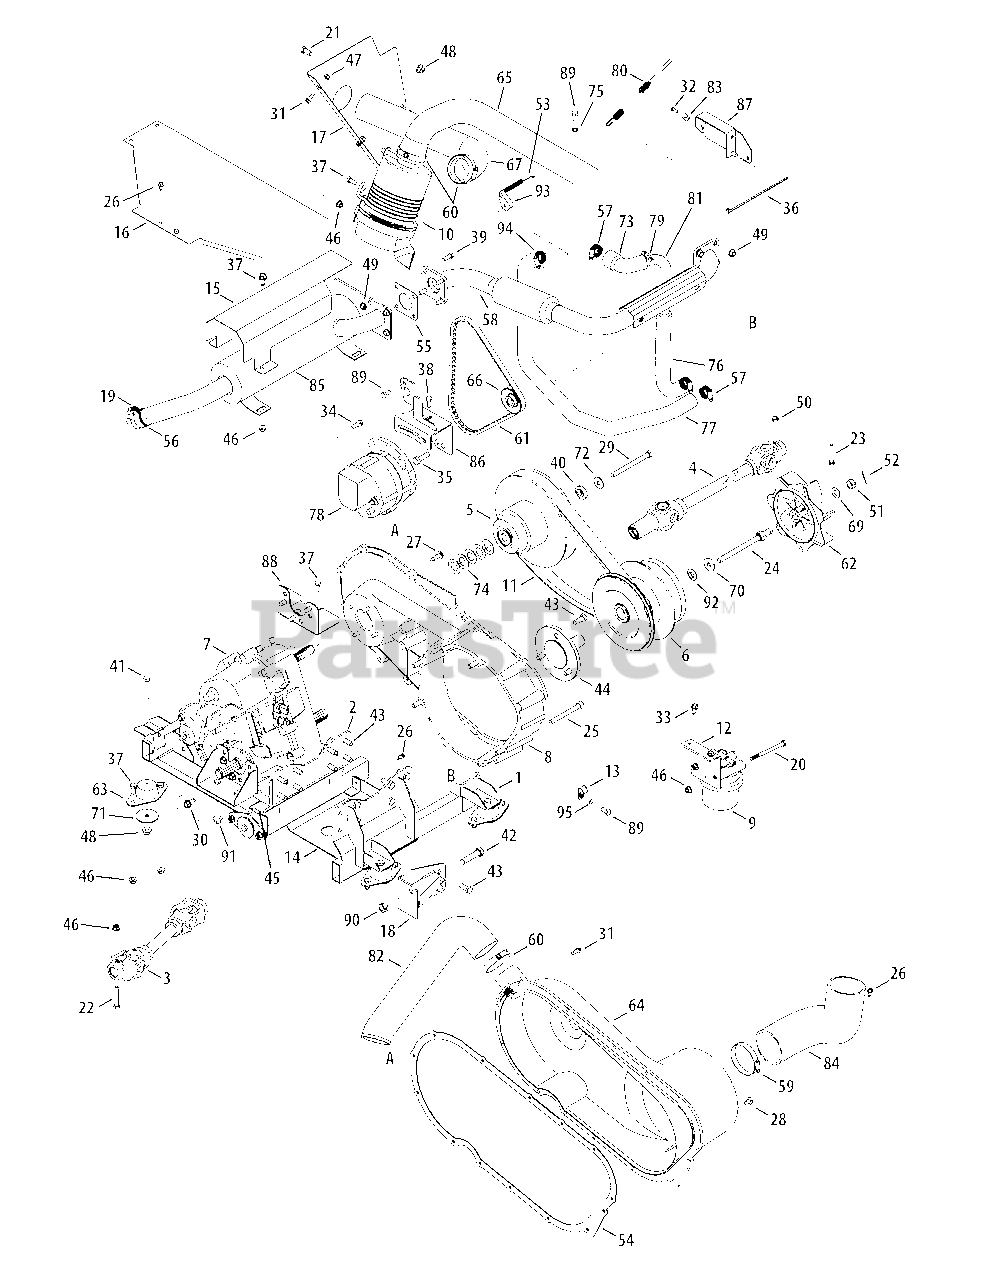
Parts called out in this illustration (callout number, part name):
1	Tray Assembly, Engine, Yanmar
2	Tray Assembly, Engine, Trans
3	Shaft Assembly, Rr/prop
4	Shaft Assembly, Frt/prop, Hilliard
5	Clutch Assembly, Cvt, Driven
6	Clutch Assembly, Driver, Yanmar
7	Case Assembly, Transfer
8	Housing Assembly, Cvt, Machine
9	Filter Assembly, Diesel
10	Filter Assembly, Air Cleaner
11	Belt, Cvt, 4x4
12	Bracket, Fuel Filter, Yanmar
14	Shield, Oil, Engine
15	Exhaust, Shield, Heat
16	Plate, Heat, Shield, Yanmar
18	Bracket Mount, Lower, Alternator
20	Hex Head Screw, 5/16-18, 4.00
21	Hex Head Screw, 3/8-16, .75
22	Hex Head Screw, 5/16-18, 2.00
23	Hex Head Screw, 5/16-18, 1.875
24	Hex Head Screw, 7/16-20, 5.00
25	Screw, M10-1.50
26	Screw, Tt, 1/4-20, 0.500, Hxindwsh
27	Screw, Tt, 5/16-18, 1.000, Hxind.
28	Screw, B, 5/16-12, 0.500, Hxindwsh
29	Hex Head Screw, 3/8-24, 2.50
30	Screw, Tt, 3/8-16, 0.750, Hxindwsh
31	Screw, Tt, 1/4-20, 0.750, Hxindwsh
32	Screw, #10-16, 0.625, Hxindwsh
33	Screw, 5/16-18, 0.750, Hxindwsh
34	Hex Head Screw, 5/16-18, .875
35	Hex Head Screw, M8-1.5, 35 mm
36	Tie, Cable
37	Hex Head Screw, 5/16-18, .75
38	Hex Head Screw, 1/4-20, .75
39	Hex Head Screw, 5/16-18, .875
40	Spacer, Shoulder
41	Hex Head Screw, 3/8-16, 2.00
42	Hex Head Screw, 1/2-13, 2.00
43	Hex Head Screw, M10-1.5, 25mm
44	Shaft, Output, Yanmar, Tapered
46	Nut, Flange Lock, 5/16-18, Nylon
47	Nut, Flange Lock, 1/4-20, Nylon
48	Nut, Flange Lock, 3/8-16, Nylon
49	Nut, Flange Lock, 5/16-18, Sd Lk
50	Nut, Hex Lock, 5/16-18, Ctrlk
51	Nut, Hex, 1/2-20, Gr5, Slot
52	Pin, Cot, 3/32, 1.0
53	Spring, Extension
54	Gasket, CVT Cover
55	Gasket, Engine
56	Spark Arrester Screen
57	Clamp, Hose, Adj
58	Pipe, Exhaust, Yanmar
59	Clamp, Hose, Adj
60	Clamp, Hose, Adj 2-3"
62	Impeller, Blo
63	Compression Mount, Eng, Head
64	Cover, Cvt
65	Hose, Air Inlet, Yanmar
67	Hose, Air Inlet
68	Washer, Flat, .330 x .630 x .0635
69	Washer, Flat, .510 x 1.00 x .060
70	Washer, Flat, .450 x 1.250 x .164
71	Washer, Flat, .38 x 2.00 x .12
72	Washer, Bell, .396 x 1.140 x .095
73	Tube, Upr, rr, Rdtr, Yanmar
74	Washer, Flat, .793 x 1.368 x .025
75	Washer, Lock, 5/16 Ext Tooth
76	Tube, lwr, rdtr
77	Hose, Rdtr, Rr, Yanmar
78	Alternator, Aux, 65 Amp
79	Fitting, Petcock, 1/8"
80	Cable, Throttle Control, Yanmar
81	Tube, Rdtr
82	Hose, CVT, Exhaust
83	Clamp, Casing
84	Tube, Cvt, Intake
86	Assembly Mount, Alternator
87	Bracket, Throttle Mount
88	Bracket, Transmission Mount, rr
89	Hex Head Screw, M8-1.25
90	Nut, Hex Lock, 1/2-13
91	Nut, M8-1.25
92	Spacer, Shoulder
93	Bracket, Throttle, Spring, Return
94	Clamp, Hose, Adj
95	Washer, Flat 1/4"
